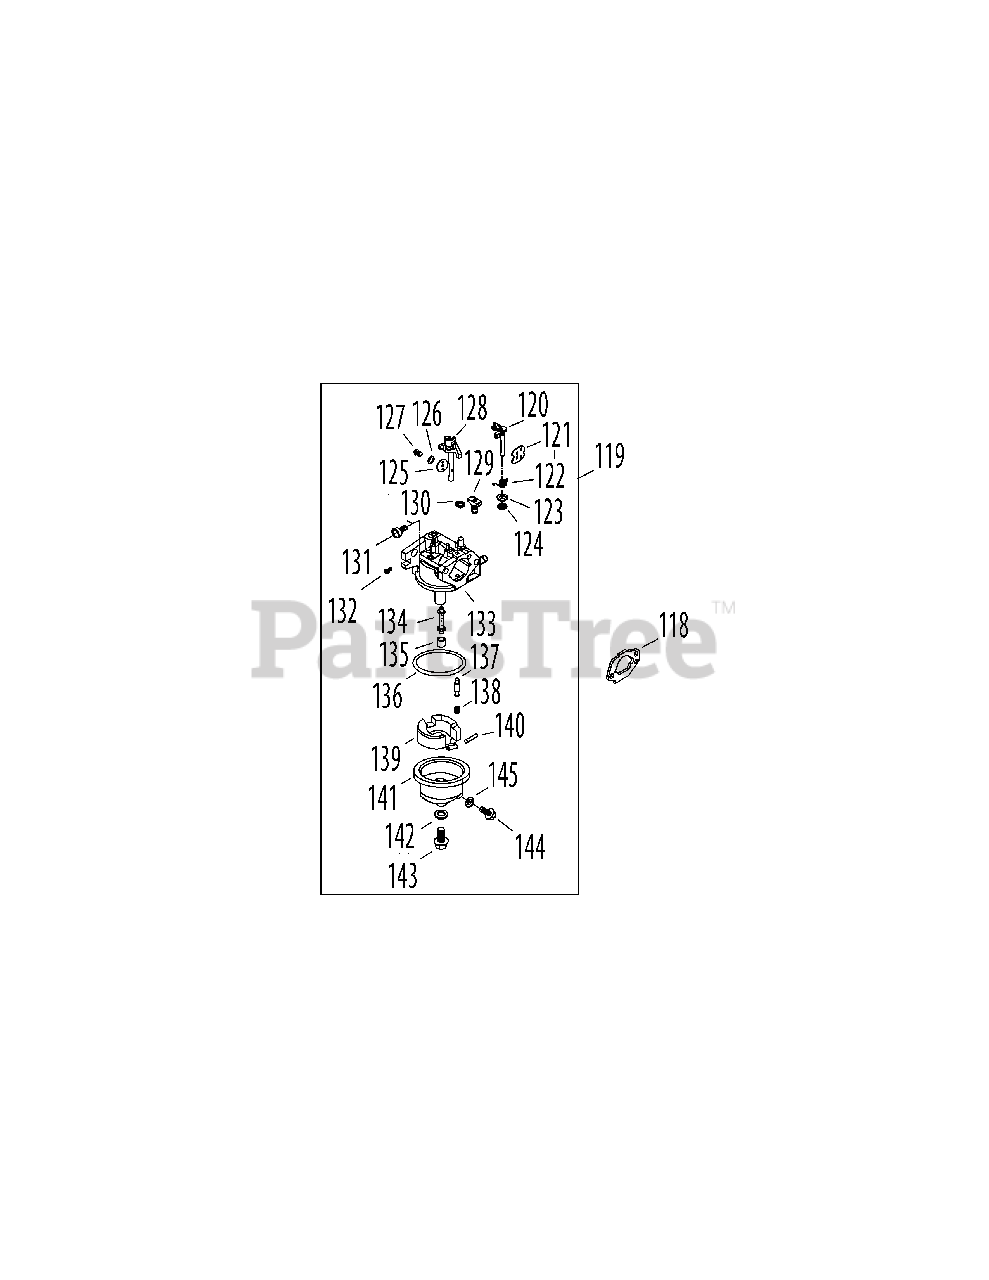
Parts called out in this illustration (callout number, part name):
118	Carburetor Gasket Plate
119	Carburetor Assembly
120	Choke Shaft
121	Choke Plate
122	Choke Return Spring
123	Choke Shaft Washer
124	Fiber O-Ring
125	Throttle Plate
126	Throttle Plate Lock Washer
127	Throttle Plate Screw
128	Throttle Shaft
129	Idle Jet Assembly
130	Fiber O-Ring
131	Idle Speed Adjusting Screw
132	Idle Mixture Screw
133	Carburetor Body
134	Main Nozzle / Emulsion Tube
135	Main Jet
136	Fuel Bowl O-Ring
137	Needle Valve
138	Needle Valve Spring
139	Float
140	Float Pin
141	Fuel Bowl
142	Fuel Bowl Gasket
143	Fuel Bowl Mounting Bolt
144	Fuel Drain Plug
145	Fuel Drain Plug Gasket
